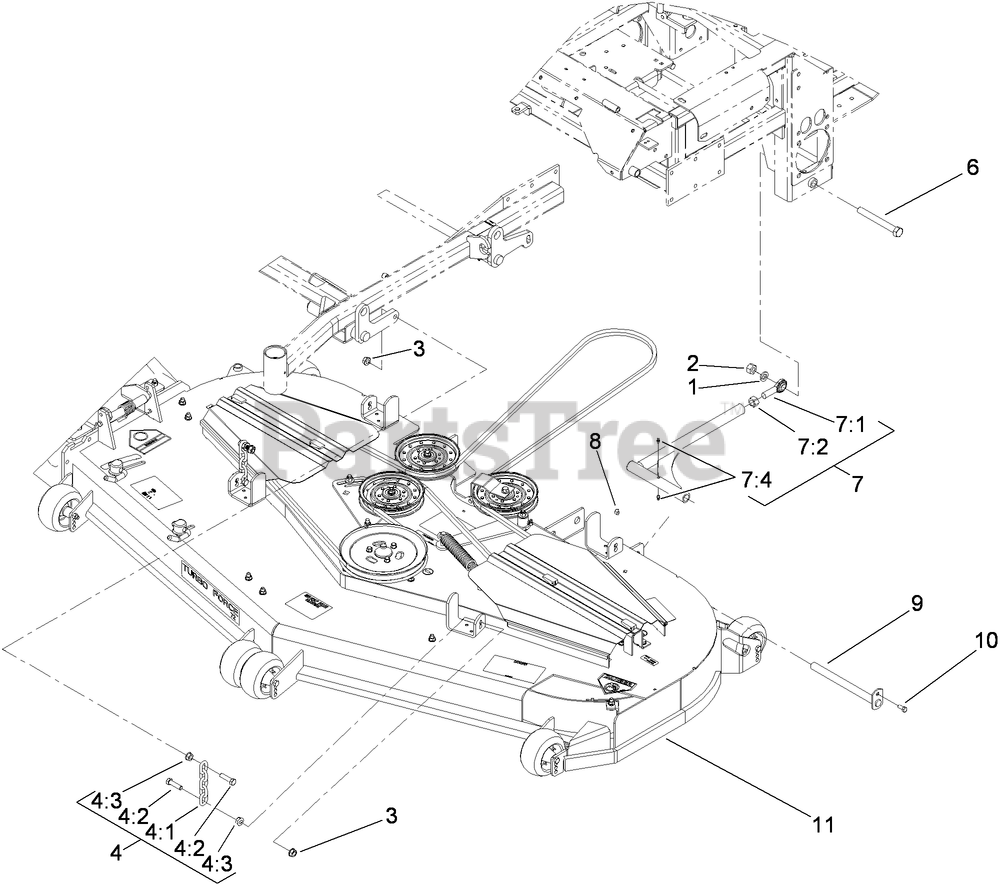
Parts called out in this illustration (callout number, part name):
1	WASHER-LOCK
2	NUT-HEX
3	NUT-HF
4	DECK CHAIN ASM
4:1	CHAIN-LIFT, DECK
4:2	SCREW-HH
4:3	NUT-HF
6	SCREW-HH
7	STRUT ASM
7:1	BALLJOINT-SPHERICAL
7:2	NUT-HEX
7:4	FITTING-GREASE
8	NUT-LOCK, NI
9	PIN-STRUT
10	SCREW-HH
11	DECK ASM
